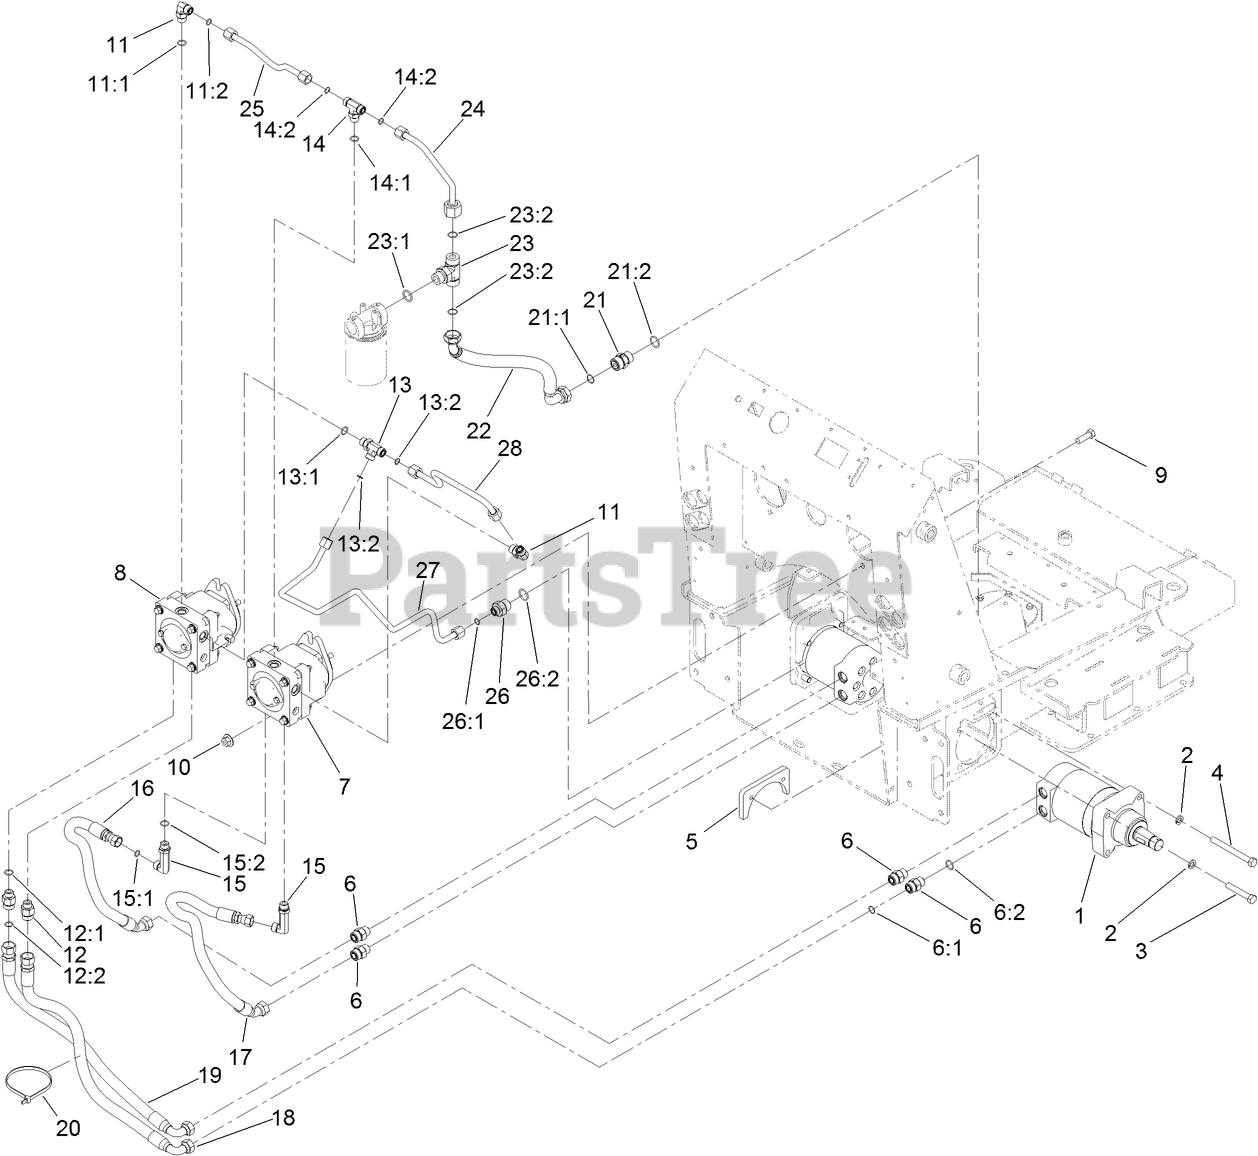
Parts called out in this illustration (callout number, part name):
1	HYD MOTOR ASM
2	SCREW-HH
3	SCREW-HH, TAP
4	SCREW-HH
5	PLATE-MOUNTING
6	FITTING-STRAIGHT
6:1	O-RING
6:2	O-RING
7	PUMP-HYD, RH
8	PUMP-HYD, LH
9	SCREW-HH
10	NUT-LOCK, FLANGE
11	FITTING-ELBOW, 90 DEG
11:1	O-RING
11:2	O-RING
12	FITTING-STRAIGHT
12:1	O-RING
12:2	O-RING
13	FITTING-TEE
13:1	O-RING
13:2	O-RING
14	FITTING-HYD, TEE
14:1	O-RING
14:2	O-RING
15	FITTING-ELBOW 90 LONG
15:1	O-RING
15:2	O-RING
16	HOSE-HYD
17	HOSE-HYD
18	HOSE-HYD
19	HOSE-HYD
20	TIE-CABLE
21	VALVE-CHECK, HYD
21:1	O-RING
21:2	O-RING
22	HOSE-HYD
23	FITTING-TEE
23:1	O-RING
23:2	O-RING
24	TUBE-HYD
25	TUBE-HYD
26	FITTING-STR
26:1	O-RING
26:2	O-RING
27	TUBE-HYD
28	TUBE-HYD
